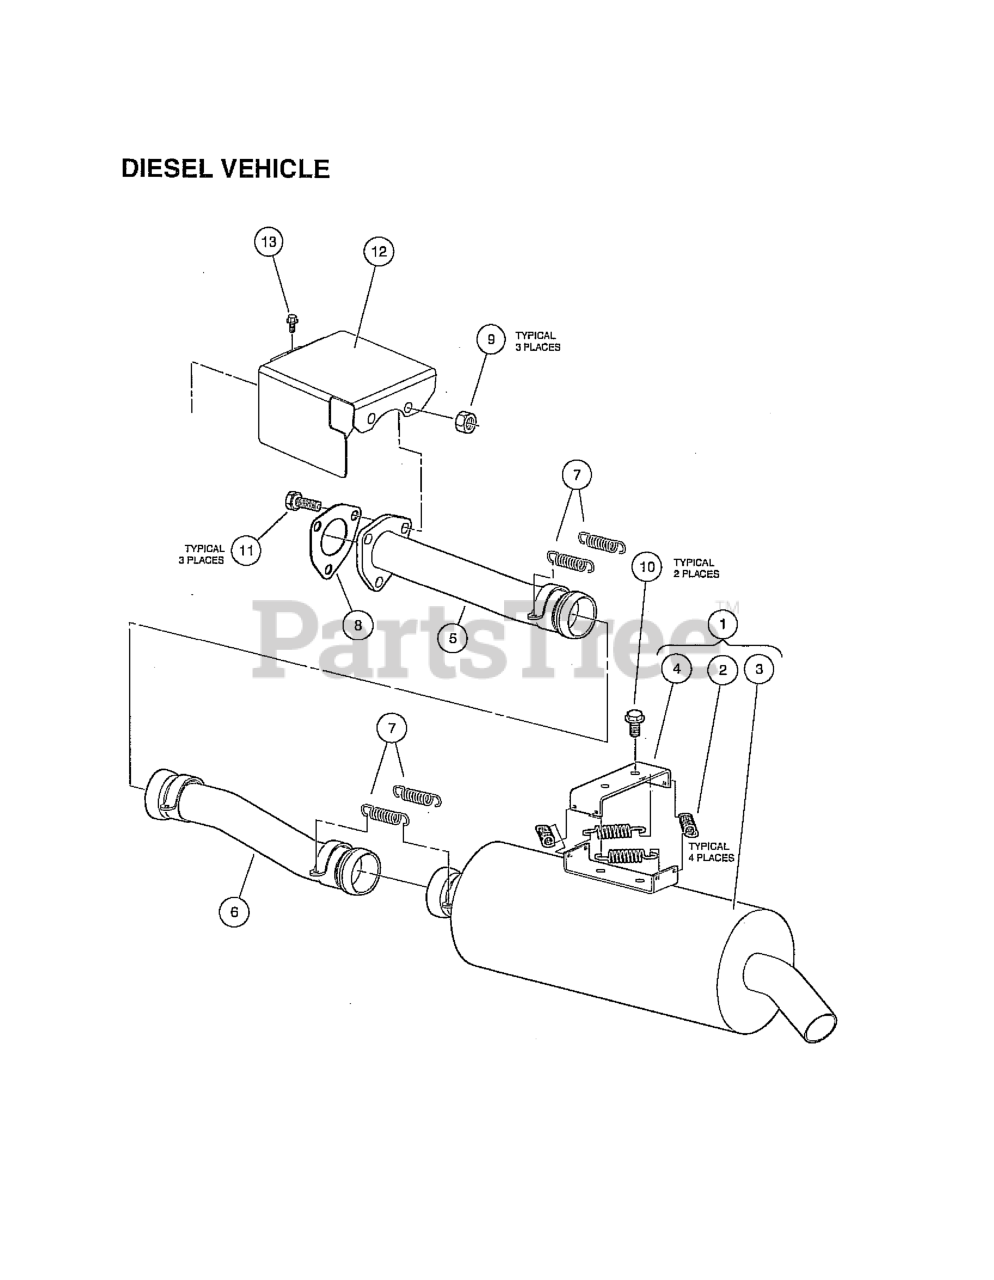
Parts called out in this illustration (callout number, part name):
1	ASM, MUFFLER
2	SPRING, EXHAUST
5	PIPE, EXHAUST DIESEL MAIN
6	PIPE, EXHAUST INTERMEDIATE
7	SPRING, EXHAUST
8	GASKET, EXHAUST DIESEL
9	NUT FLG, M8 X 1.25 MECH DEF
10	BOLT FLG, M8X1.25X16 LOCTITE
11	BOLT, M8X1.25X40 LOCTITE
12	SHIELD, DIESEL EXHAUST
13	BOLT, D722, EXHST MANFLD COVER
